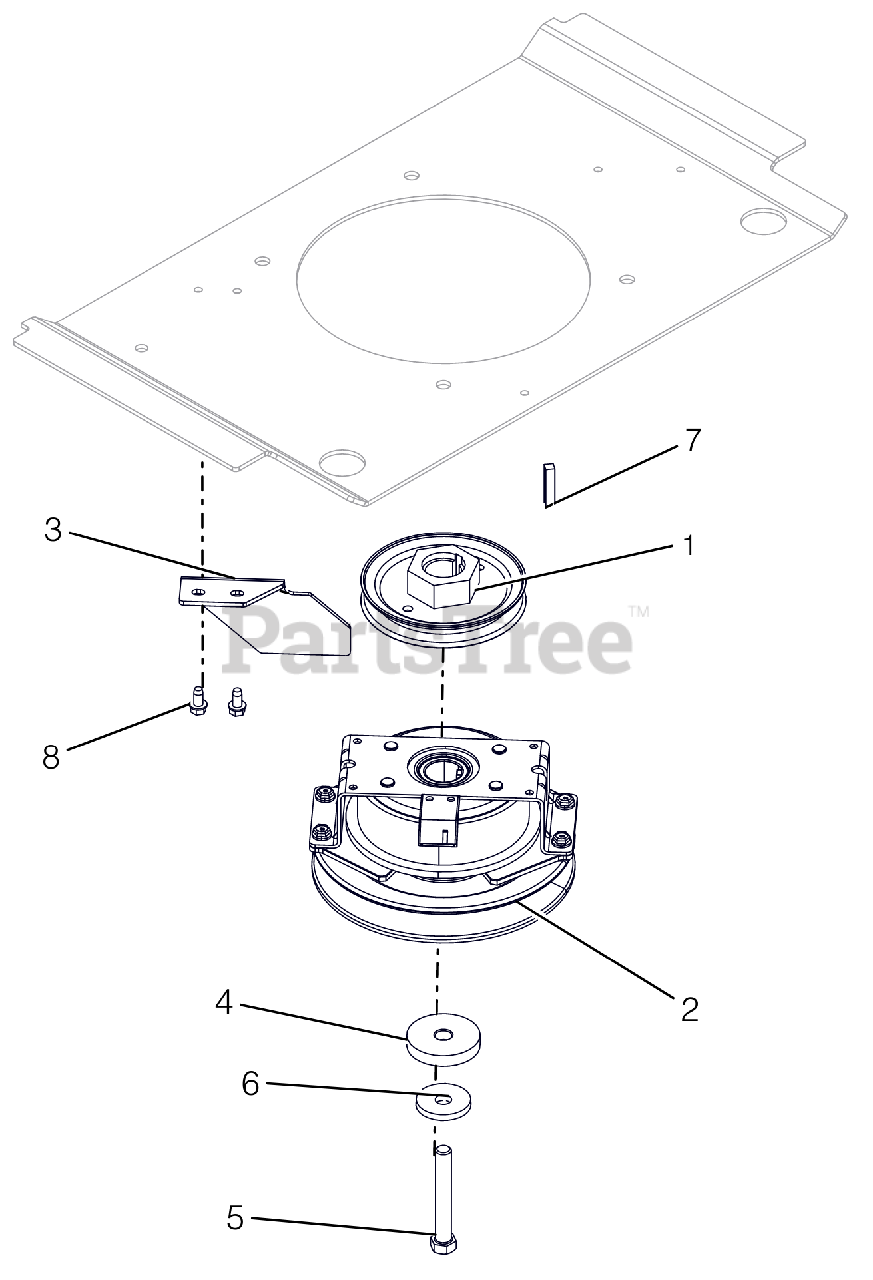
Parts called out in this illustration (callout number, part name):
1	WLDMT,PULLEY-4.50ODX1.003
2	CLUTCH, OGURA
3	BRKT, CLUTCH STOP HD
4	SPACER, .474/.459X2.00X.350
5	BLT-HEX .44-20X3 G8YZ NYTORQ
6	WASHER, 7/16" SPRING DISK
7	KEY-SQ .25 X 1.25 X .25 SAE
8	SCR-TAP .25-20X.50 HWH TR YWZ
